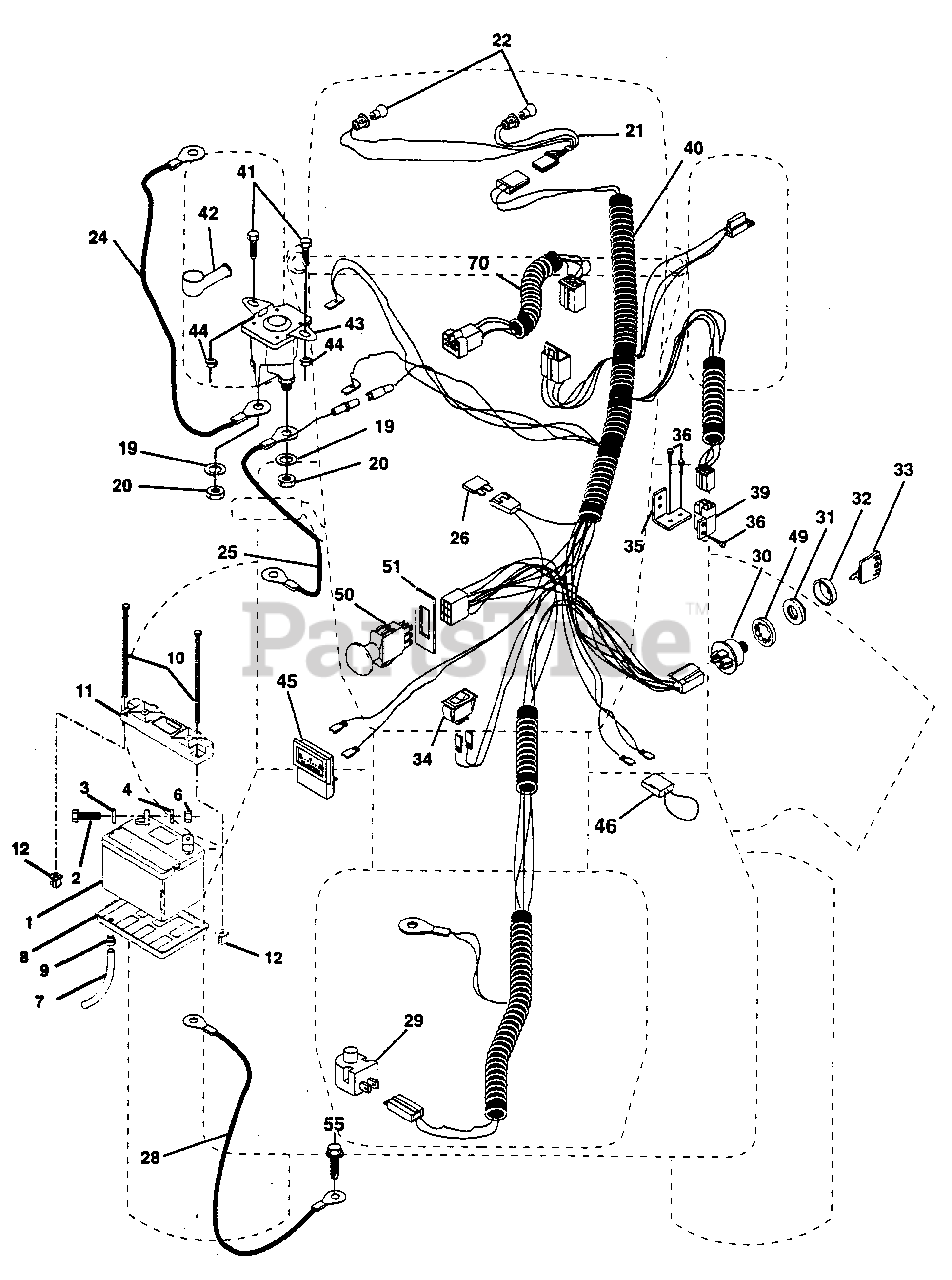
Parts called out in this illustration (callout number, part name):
1	Battery (AYP part number)
2	Bolt, Hex Head 1/4-20 x 3/4 (AYP part number)
3	Washer 9/32 x 5/8 x 16 Gauge (AYP part number)
4	Washer, Lock 1/4 (AYP part number)
6	Nut, Hex 1/4-20 (AYP part number)
7	Tube, Tray, Battery (AYP part number)
8	Tray, Battery (AYP part number)
9	Clamp, Hose (AYP part number)
10	Bolt, Battery Fnt 1/4-20 x 7-1/2 Zinc (AYP part number)
11	Holddown Battery Dash Mount (AYP part number)
12	Nut, Push Nylon 1/4" Battery Fnt (AYP part number)
19	Washer, Lock 1/4 (AYP part number)
20	Nut, Hex, Jam 1/4-20 (AYP part number)
21	Harness, Socket, Light (w/4152J) (AYP part number)
22	Bulb, Light (AYP part number)
24	Cable, Battery 6 Ga. 11" Red (AYP part number)
25	Cable, Battery 6 Ga. 22" Red w/16 Wire (AYP part number)
26	Fuse (AYP part number)
28	Cable, Ground 21" Blk 6 Ga. 90T (AYP part number)
29	Switch, Plunger (AYP part number)
30	Switch, Ignition (AYP part number)
31	Nut, Ignition (AYP part number)
32	Bezel, Ignition (AYP part number)
33	Key, Molded (AYP part number)
34	Switch, Light (AYP part number)
35	Bracket Switch Interlock (AYP part number)
36	Screw, Hex Tap #10-24 UNC (AYP part number)
39	Switch, Clutch, Interlock (AYP part number)
40	Harness, Ignition (AYP part number)
41	Bolt, Hex 1/4-20 x 3/4 (AYP part number)
42	Cover, Terminal (AYP part number)
43	Solenoid (AYP part number)
44	Nut, Hex, Keps 1/4-20 (AYP part number)
45	Ammeter Rectangular (AYP part number)
46	Protection Wire Loop
49	Washer, Lock Internal Tooth 5/8 (AYP part number)
50	Switch, P.T.O. (AYP part number)
51	Ring, Retainer PTO (AYP part number)
55	Screw, Thdrol. 5/16-18 x 1/2 Tyt (AYP part number)
70	Harness Eng. CV18 Lt/Yt
